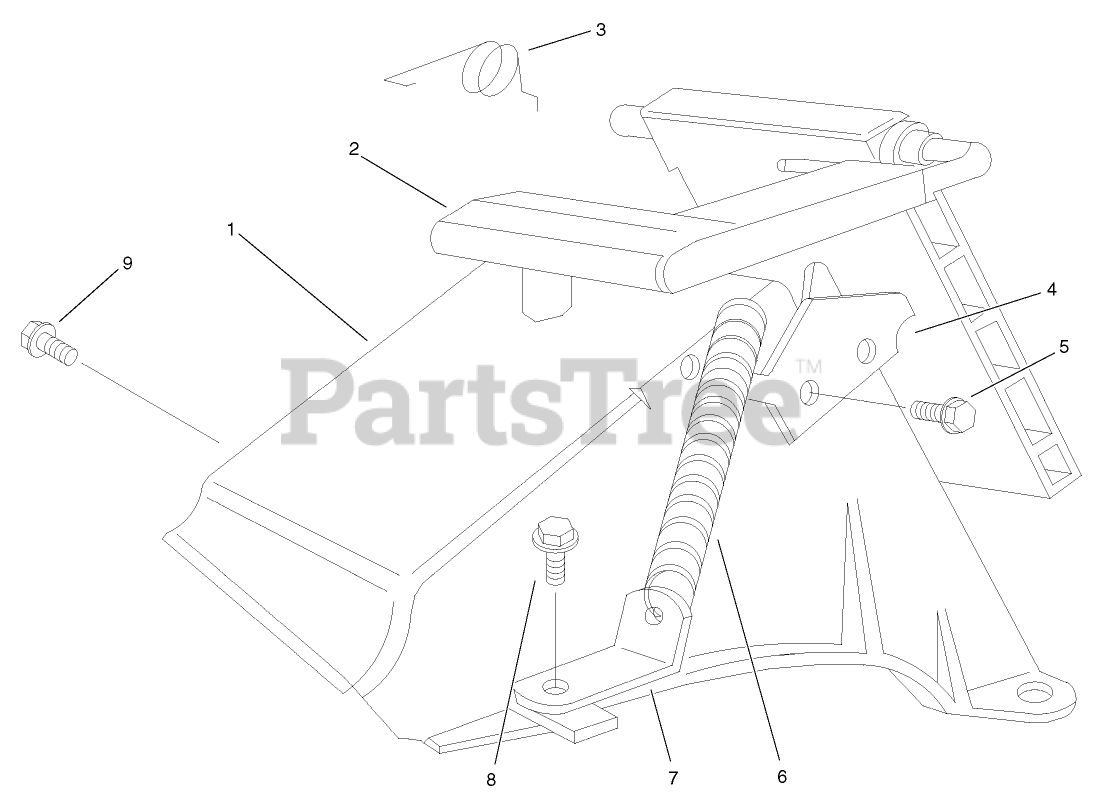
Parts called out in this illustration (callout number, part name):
1	TUNNEL-DISCHARGE
2	DISCHARGE DOOR ASM
3	SPRING-DOOR
4	LATCH-PLATE
5	SCREW-PLASTITE
6	RETAINER-DOOR
7	BRACKET-SPRING
8	SCREW-HWH
9	SCREW AND WASHER ASM
